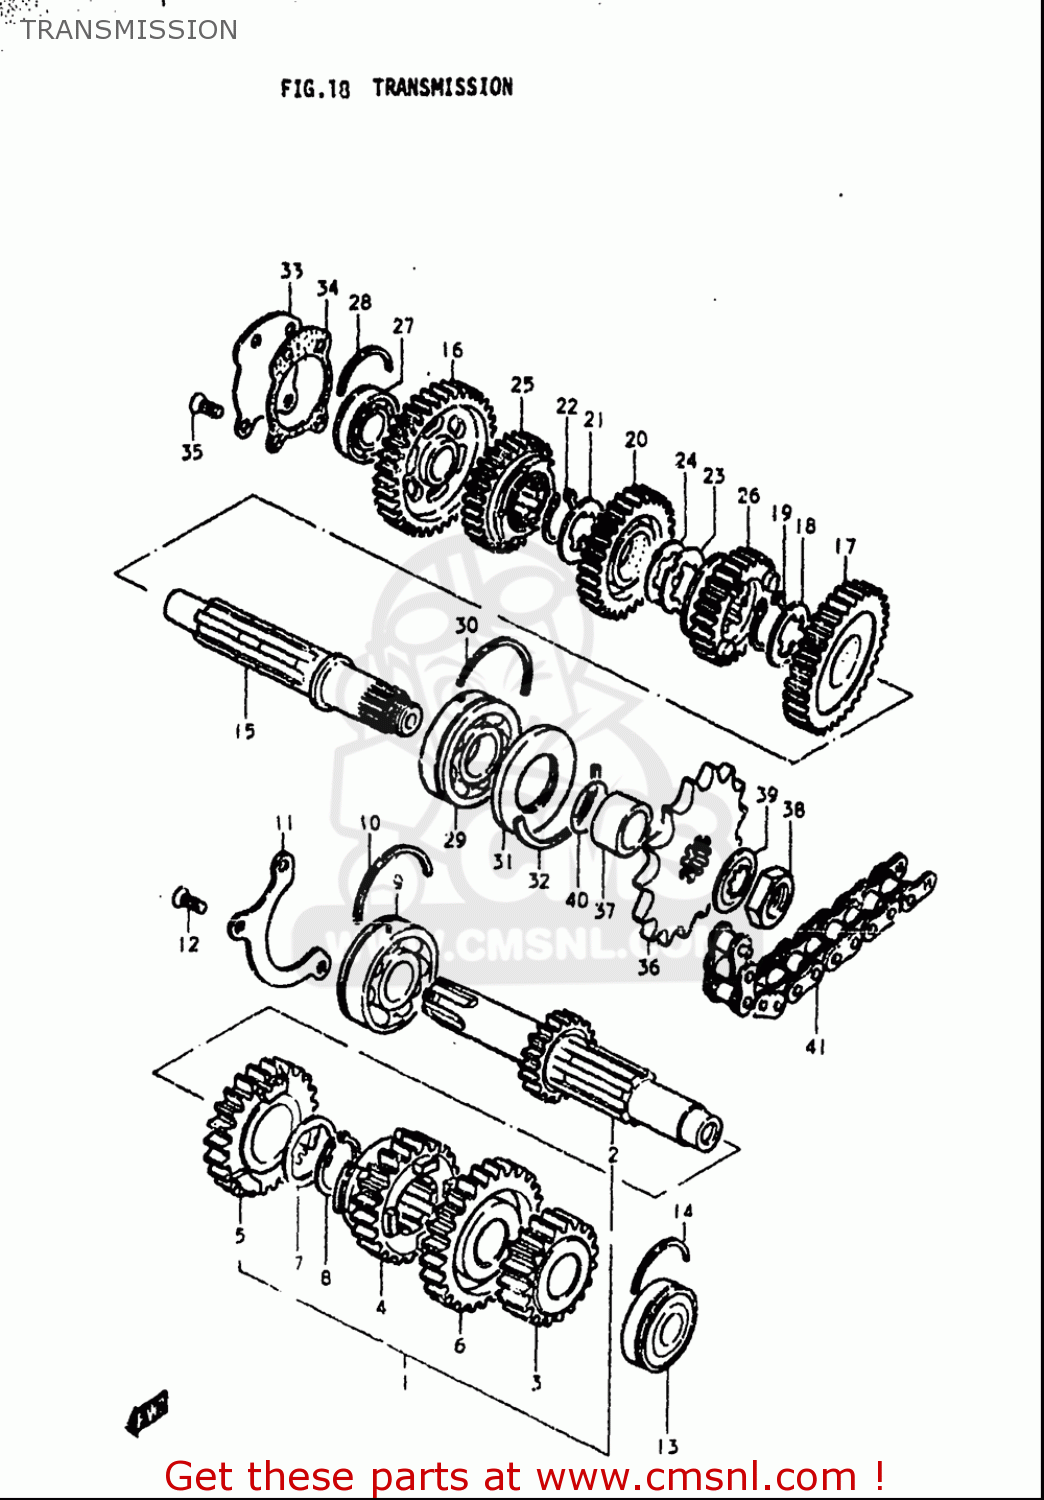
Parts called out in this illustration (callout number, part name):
6	GEAR,FIFTH DRIVE
7	WASHER,LOCK
8	CIRCLIP
9	BEARING(25X62X17)
10	C RING
11	RETAINER,CNTR SHAFT BEARING
12	SCREW
13	BEARING(20X47X14)
14	C RING
18	WASHER,LOCK
19	CIRCLIP
21	WASHER,LOCK
22	CIRCLIP
23	WASHER,LOCK
24	WASHER
27	BEARING(20X47X14)
28	C RING
29	BEARING(25X62X17)
30	C RING
31	SEAL,OIL(32X62X7)
32	C RING
33	PLATE,DRIVE SHAFT
34	GASKET,DRIVE SHAFT PLATE (NAS)
35	SCREW
36	SPROCKET,ENGINE (NT:15)
37	SPACER(25X32X18.6)
38	NUT
39	WASHER,LOCK
40	O RING(D:1,ID:24.5)
41	CHAIN,DRIVE(DID630YL,96LE)
